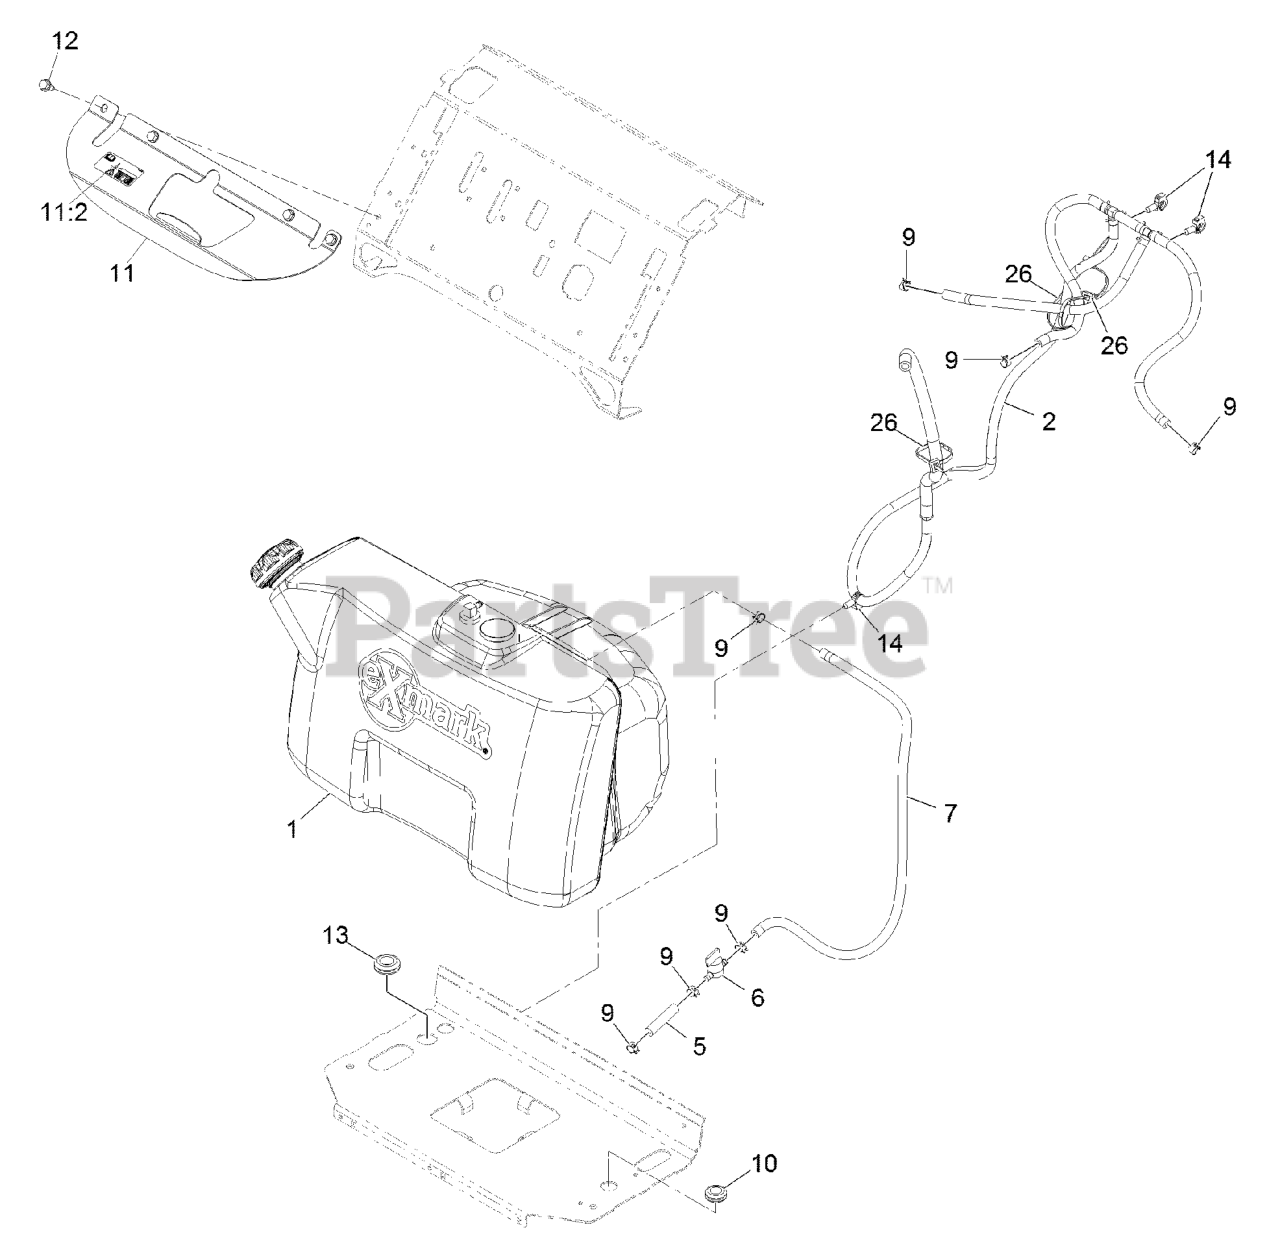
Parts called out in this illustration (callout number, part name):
2	VENT ASM
5	HOSE-FUEL
6	VALVE-FUEL
7	HOSE-FUEL
9	CLAMP-HOSE
10	GROMMET
11	BRACKET-TANK
11:2	Decal-Fill, Fuel
12	Screw-HWH 5/16-18 X 3/4 Tf
13	GROMMET
14	CLIP-HARNESS
26	TIE-CABLE
